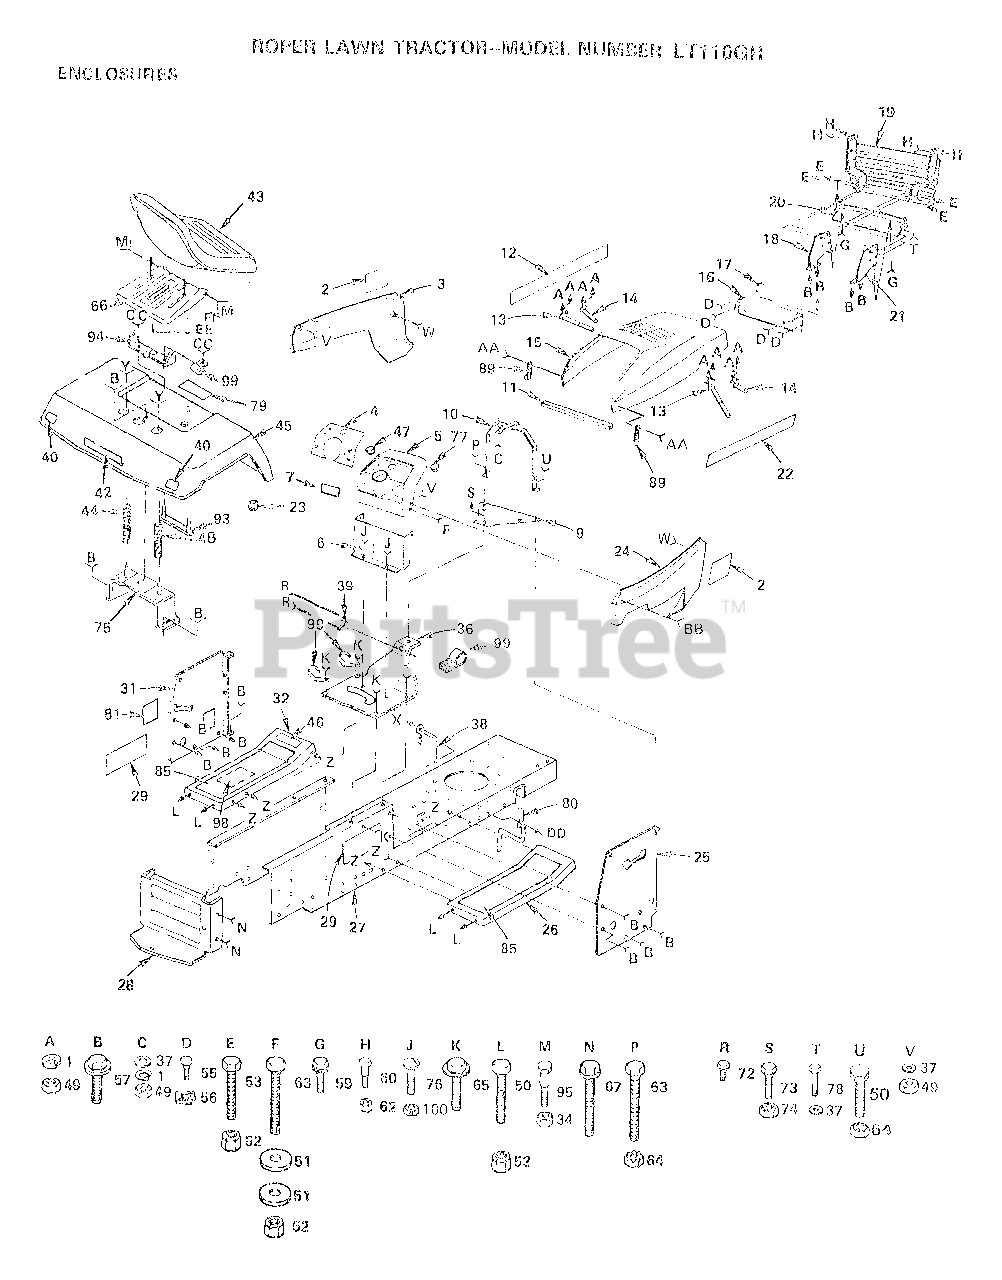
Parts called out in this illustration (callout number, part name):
1	LOCKWASHER
6	DASH ASSY LT
10	SUPPORT ASSY LT
11	FOAM-STRIP LT
17	LENS LT
18	SUPPORT-GRILL LT
23	GROMMET T
25	PANEL DASH RH YT
31	PANEL DASH HYT
32	FOOTREST LH YT
37	WASHER PM
40	REFLECTOR-TAIL YT
47	PLUG-DASH T
51	WASHER
53	BOLT
56	"""J"" FASTENER LT"
57	SCREW
59	SCREW
60	BOLT T
64	NUT
65	SCREW LT
67	SCREW
73	BOLT
76	SCREW
77	PLUG BUTTON T
78	SCREW HEX CRT
89	HOOD LATCH T
99	CLIP T
101	WASHER
